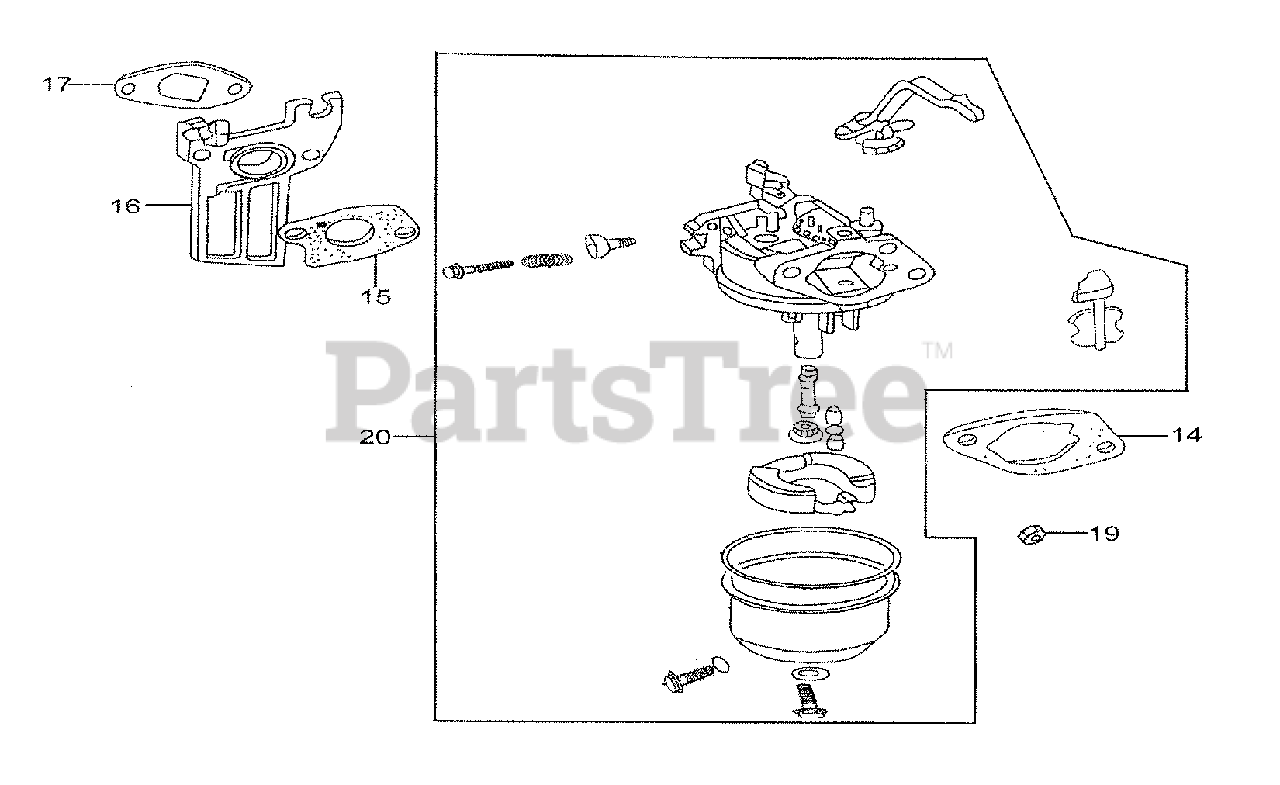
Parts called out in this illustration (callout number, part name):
14	GASKET, AIR/C
15	GASKET, CARB
16	INSULATOR, CARB
17	GASKET, INLET
19	NUT, FLANGE 6MM
20	CARBURETOR ASSY, (CARB)
